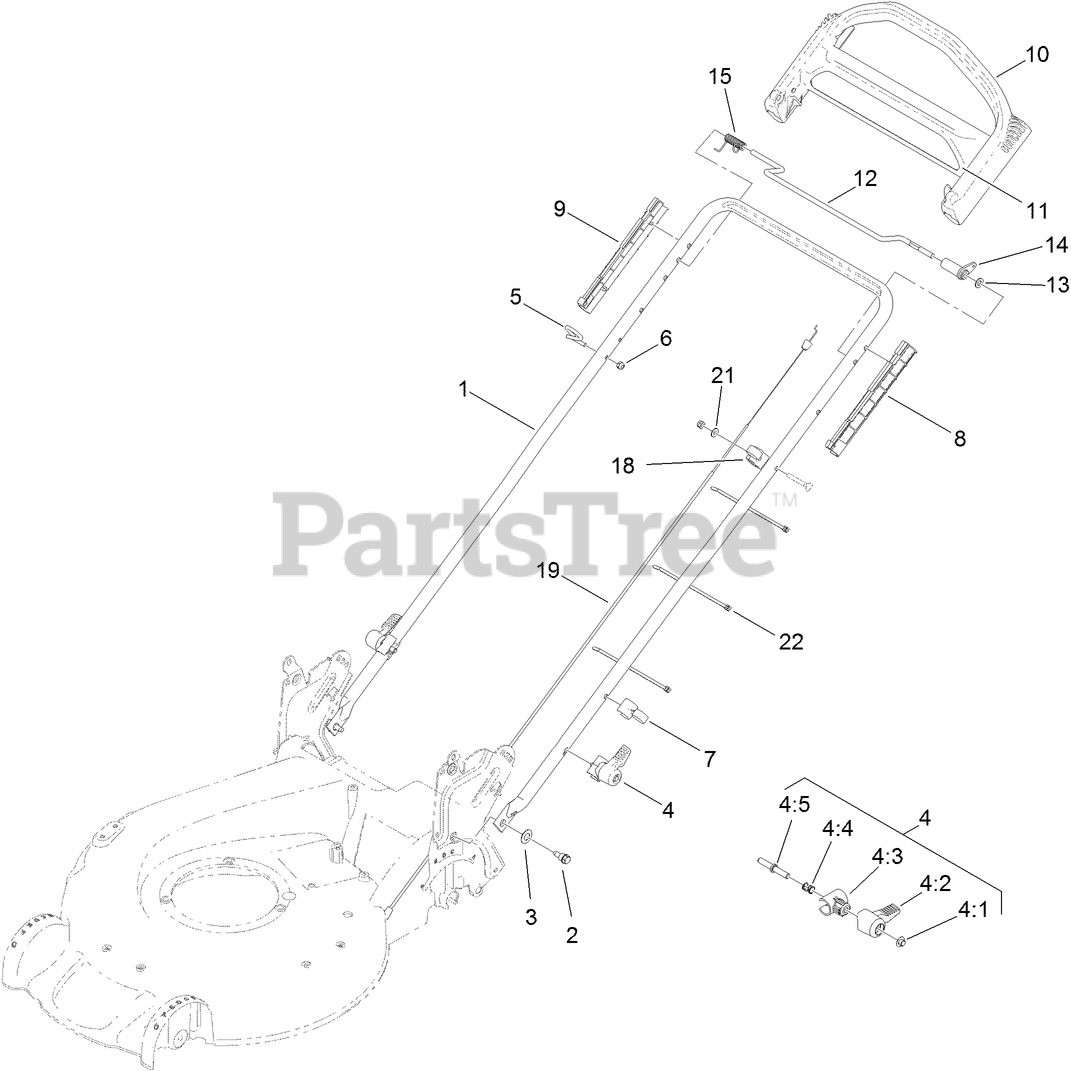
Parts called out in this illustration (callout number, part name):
2	BOLT-SHOULDER
3	WASHER-SPRING, CONICAL
4	QUICK RELEASE ASM
4:2	LEVER
4:3	ANCHOR-SPRING
4:4	SPRING-COMPRESSION
4:5	ROD-RELEASE
5	GUIDE-ROPE
6	NUT-LOCK, NI
7	GUIDE-CABLE
8	GUIDE-LH
9	GUIDE-RH
10	HANDLE-CONTROL
13	WASHER-PLAIN
14	LEVER-TRACTION
19	CABLE-TRACTION
21	WASHER-FLAT
22	TIE-CABLE
